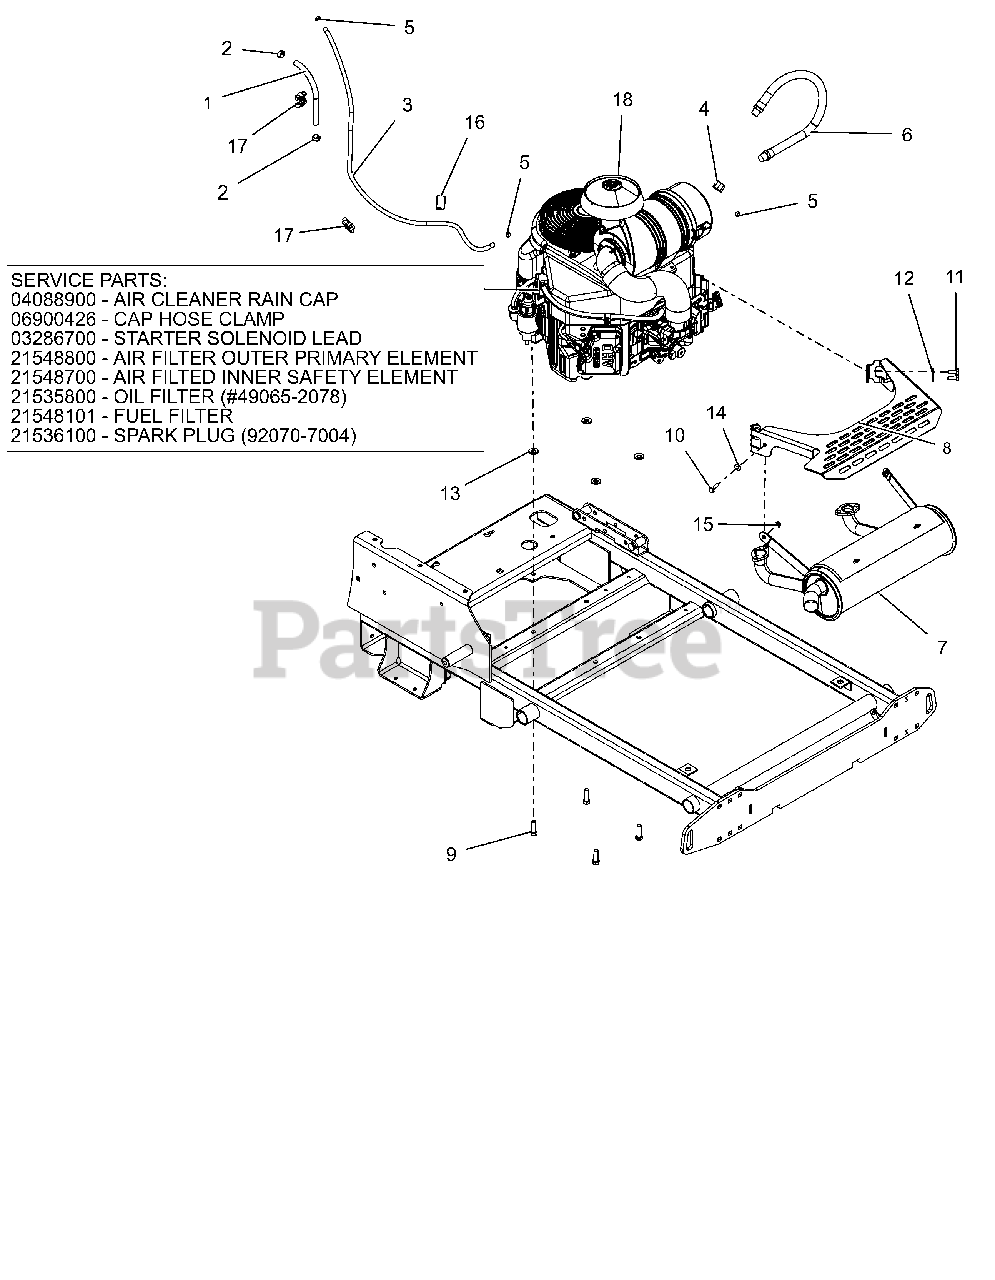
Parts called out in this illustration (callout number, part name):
1	HOSE, .25 LOW-PERM BULK GAS
2	CLAMP, FUEL LINE
3	HOSE, .188 LOW-PERM BULK GAS
4	PIPE CAP 3/8 NPT FEMALE
5	CLAMP-HOSE, SPRING .188
6	DRAIN, M20 OIL
7	EXHAUST, KAWASAKI PROSTANCE
8	SHIELD, MUFFLER
9	BLT-HEX.38-16X1.25 G5YZ NYTORQ
10	@BLT-HEX .25-20X1.00 GR5 YWZC
11	@BLT-HEX M8-1.25X20 YWZC
12	@WSHR-LK .31X.078 REG YWZC
13	WASHER, 3/8" SPRING DISC
14	@WSHR-FL-STL.281X.62X.065 YWZC
15	@NUT-LK-NYL-FLG .25-20 YWZC
16	CLAMP, COUSHIONED STEEL REV
17	CLIP, T, .38-.50
18	ENGINE, KAWASAKI FX691
18	CAP, KAW 11065-7025
18	CLAMP, HOSE #36 SS 1.813-2.75
18	LEAD - STARTER SOLENOID
18	FILTER, OUTER
18	FILTER, INNER - KAW
18	FILTER,OIL - KAW
18	OIL FILTER, KAWASAKI FR
18	PLUG, SPARK
